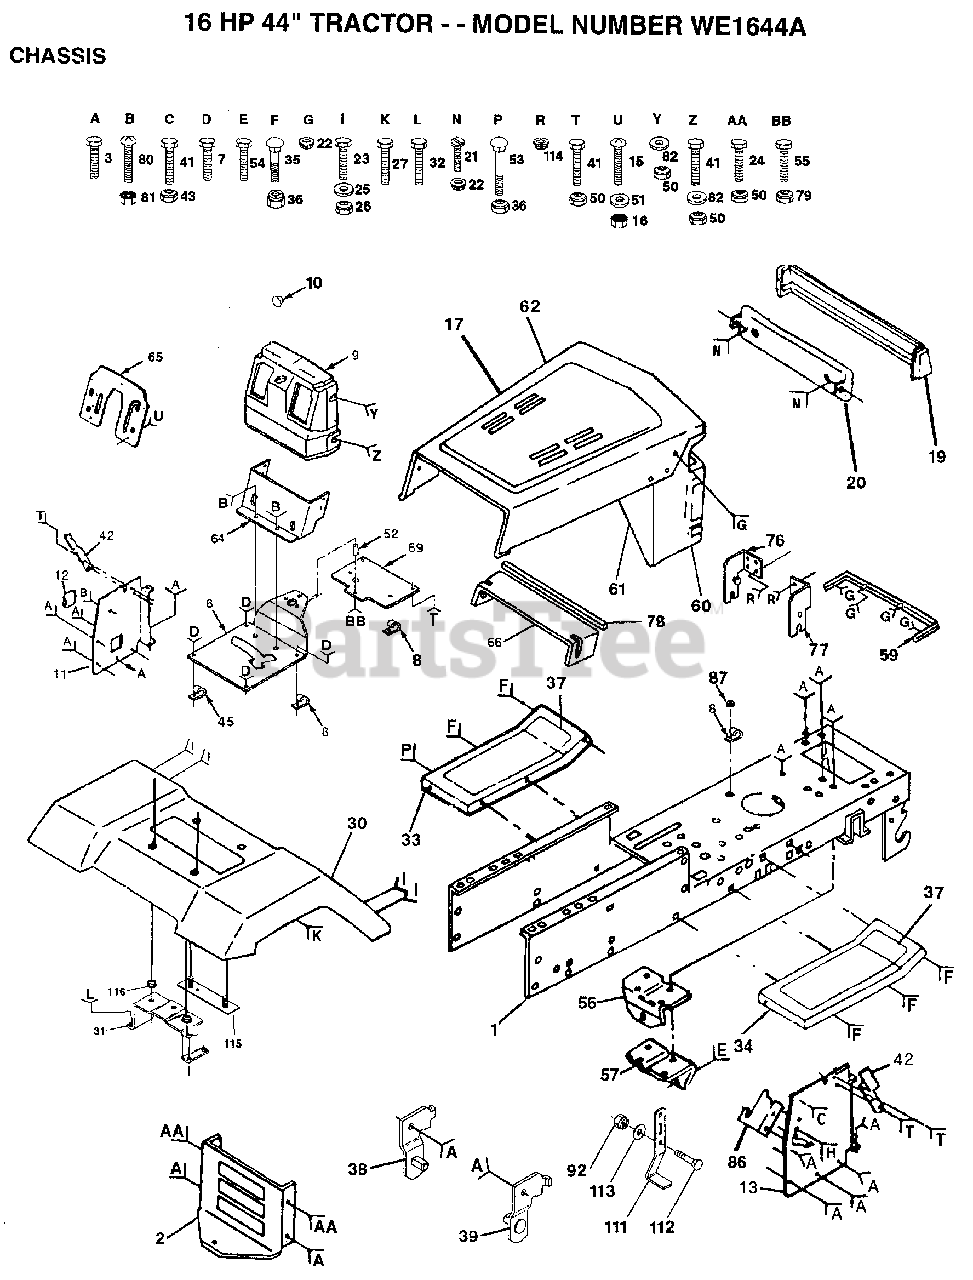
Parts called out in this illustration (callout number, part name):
2	DRAW BAR
3	SCREW
7	SCREW
8	CLIP T
10	PLUG-DASH T
11	PANEL.DASH.RH
15	SCREW
21	SCREW SPECIAL
22	PAL NUT LT
23	BOLT
25	WASHER
26	NUT
27	SCREW LT
30	FENDER.RALLY.GRN.
31	BRACKET FENDER
32	SCREW
35	BOLT
36	NUT
37	FOOTREST PAD
38	BRACKET ASM LH
39	BRACKET ASM RH
41	BOLT
42	BRACKET.ASM.SUPT.
45	"CLIP,INSULATOR"
50	NUT
51	WASHER
52	SPACER
54	SCREW LT
55	BOLT
56	SUPPORT-SADDL T
57	SUPPORT.SADDLE.FT
59	"STRAP,GRILL"
60	GRILLE ASM WELD
64	DASH-LOWER YT
65	PLATE SLKSC YT/
66	"BAFFLE,HOOD"
69	PLATE.SUPT.BATTER
76	BRACKET.RH
77	BRACKET.LH
78	FOAM STRIP T
79	NUT
80	SCREW
82	WASHER
92	NUT
111	STOP.OVER.CENTER
112	BOLT
113	WASHER GT
114	PAL NUT
115	STRAP ASM FENDER
116	NUT-PUSH YT
